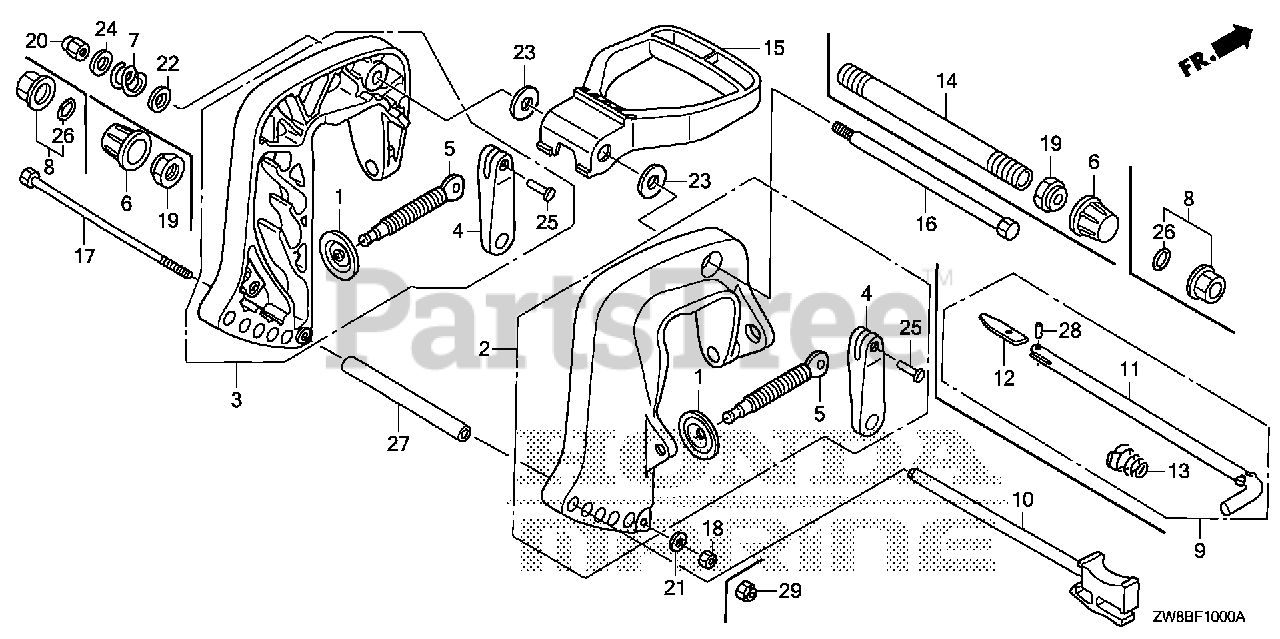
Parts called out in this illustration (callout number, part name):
1	PLATE, PUSH
2	BRACKET, R. STERN *NH282MU* (OYSTER SILVER METALLIC-U)
3	BRACKET, L. STERN *NH282MU* (OYSTER SILVER METALLIC-U)
4	GRIP, CLAMP
5	SCREW, CLAMP
7	SPRING, TILT
10	ROD, ADJUSTING
15	HANDLE, CARRYING
16	BOLT, TILTING
17	BOLT, HEX. (6X160)
18	NUT, HEX. (6MM)
20	NUT, SELF-LOCK (8MM)
21	WASHER, PLAIN (6MM)
22	WASHER, PLAIN (10MM)
23	WASHER (10MM)
24	WASHER (8MM)
25	RIVET (4X22.6)
27	COLLAR, DISTANCE (6MM)
